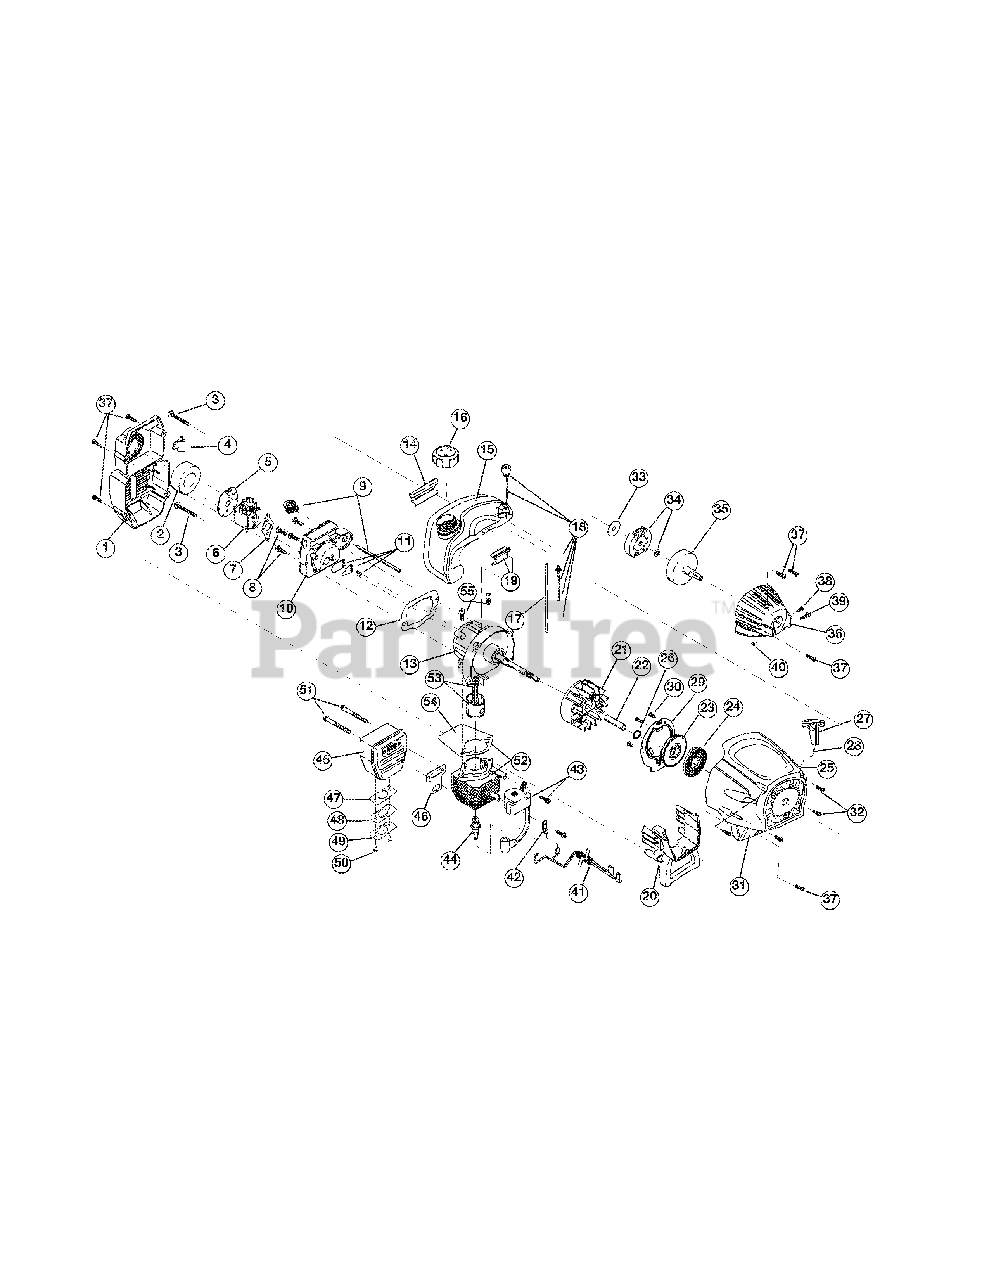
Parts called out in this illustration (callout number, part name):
1	Air Cleaner Cover Assembly (includes 2 & 37)
2	Air Cleaner Filter
3	Carburetor Mounting Screw Assembly
4	Choke Extension
5	Choke Plate
6	Carburetor Assembly (includes 7 & 9)
7	Carburetor Gasket
8	Carb Mount Screw
9	Primer & Hose Assembly
10	Carb Mount Assembly (includes 8, 11 & 12)
11	Reed Assembly
12	Carburetor Mount Gasket
13	Crankcase Service Assembly (includes 8)
14	Rear Mounting Pad
15	Fuel Tank Assembly (includes 16-18)
16	Fuel Cap Assembly
17	Fuel Return Line
18	Fuel Line Assembly
19	Front Mounting Pad
20	Shroud Extension & Stand (includes 37)
21	Flywheel Assembly
23	Recoil Pulley Assembly
24	Recoil Spring
25	Rope Guide
26	Pulley Retainer
27	Pull Handle
29	Pressure Plate Assembly
30	Plate Screw
31	Starter Housing Assembly (includes 23-30, 32 &37)
32	Housing Screw
33	Clutch Washer
34	Clutch Rotor Assembly
35	Clutch Drum Assembly
36	Clutch Cover Assembly (includes 37-40)
37	Cover Screw
38	Anti-Rotation Screw
39	Clamping Screw
40	Clamping Nut
41	Wire Leads and Sleeve
42	Ground Tab
43	Module Assembly
45	Muffler Assembly (includes 46-51)
46	Exhaust Gasket
47	Spark Arrestor Screen
48	Exhaust Hood Diverter
49	Exhaust Hood
50	Screws
51	Muffler Mounting Bolts
52	Cylinder Assembly (includes 54 & 55)
53	Piston and Rod Assembly
54	Cylinder Gasket
55	Cylinder Bolt
